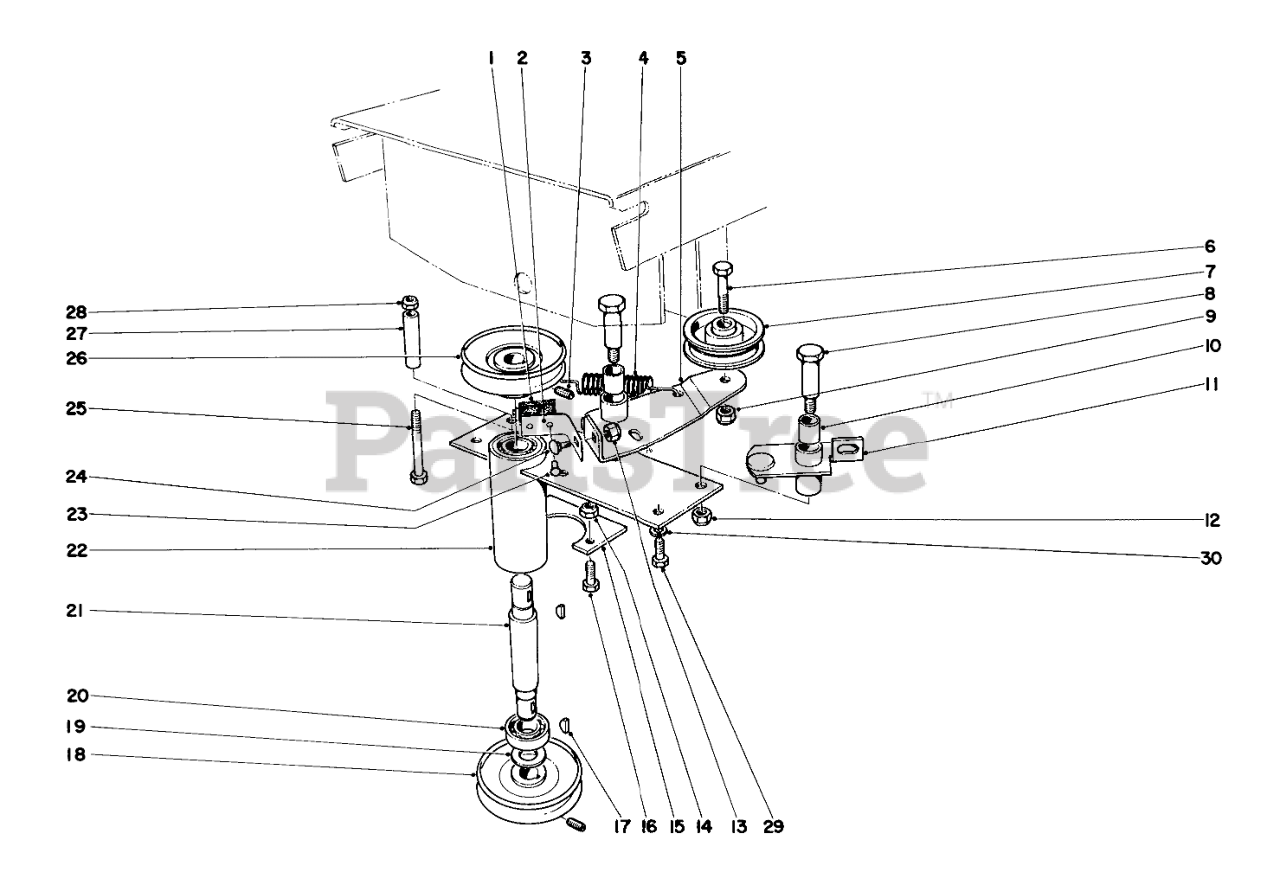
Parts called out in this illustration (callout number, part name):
1	BLADE BRAKE LINING
2	Brake Spring
3	SCREW-SET
4	Spring
5	Idler Place (Incl. Ref. #10)
6	SCREW-HH
7	Pulley
8	Shoulder Bolt
10	Bushing
11	Pivot Bracket (Incl. Ref. #lO)
14	Nut
15	Retainer Power Take Off Tube
16	SCREW-HH
17	KEY-WOODRUFF
18	Pulley
19	Bearing Washer
20	Bearing
21	Shaft
22	Power Take Off Tube
23	Rivet
24	SCREW-CARR
25	SCREW-HH
26	Pulley
27	Spacer
28	Nut
29	SCREW-HH
30	WASHER-LOCK
